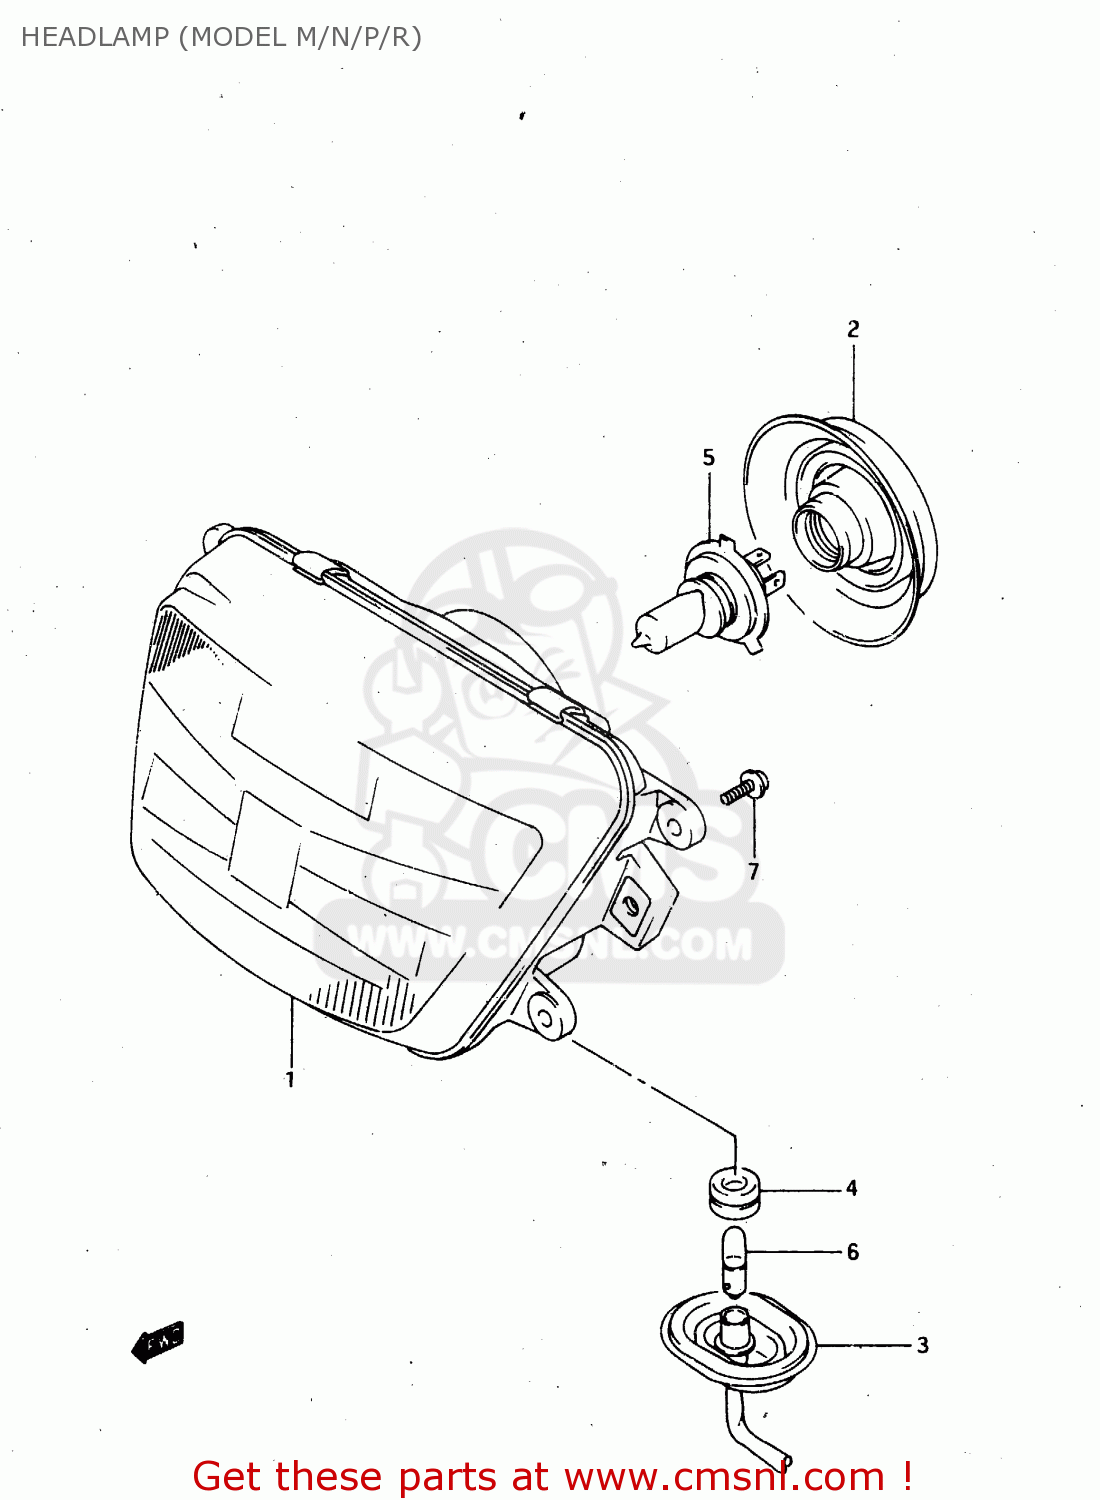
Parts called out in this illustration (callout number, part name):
1	UNIT, HEADLAMP
2	COVER,SOCKET
3	SOCKET
4	JOINT,RUBBER
5	BULB(12V60/55W,H4)
6	BULB(12V4W)
7	SCREW
